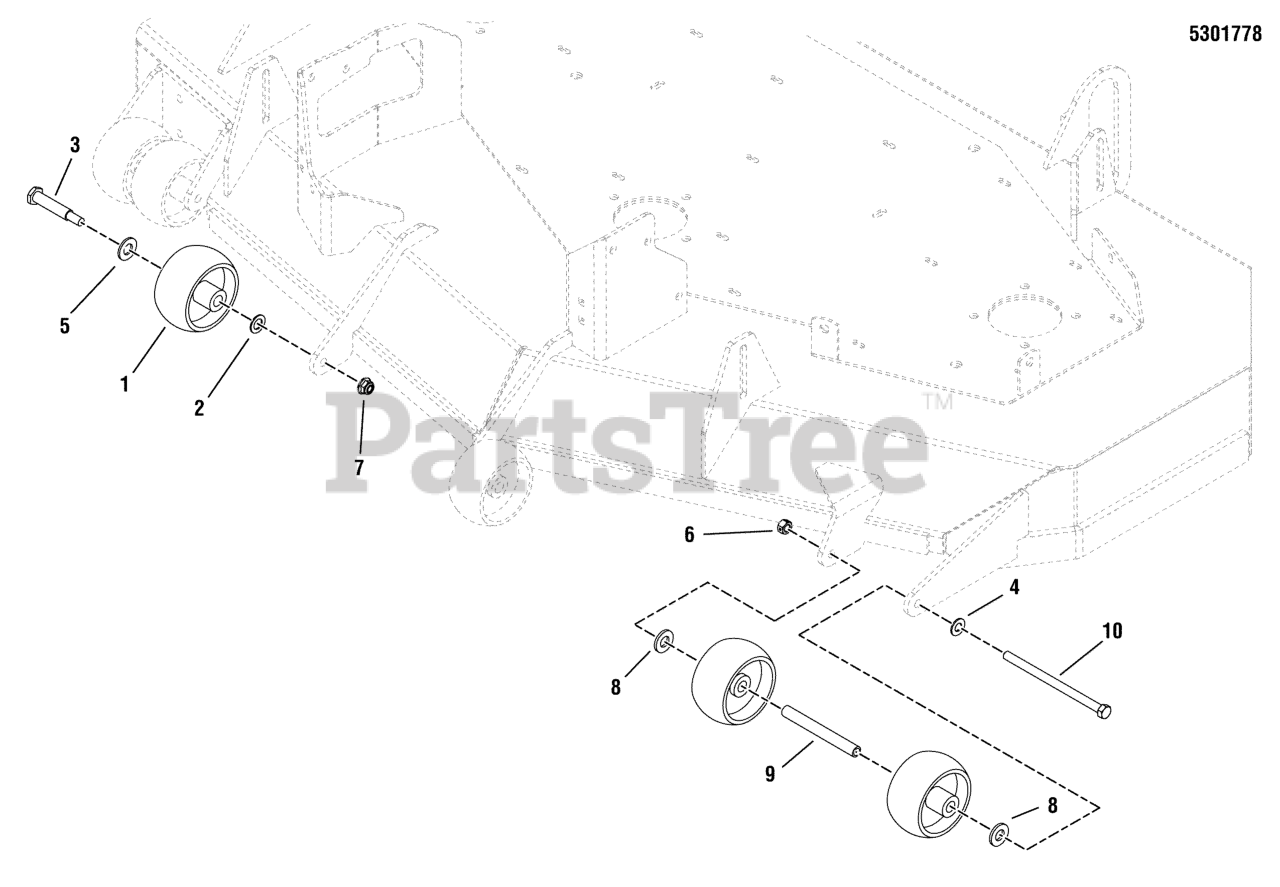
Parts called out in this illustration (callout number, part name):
1	WHEEL- 2.00 WIDE 3.88 DIA 0.531ID POLY
2	WASHER,.516IDX.875ODX.06,FLAT,ZC/CL
3	BOLT-WHEEL 3/8-16X2.781 .750 THRD YELLOW
4	WASHER, 3/8 SAE
5	WASHER, 1/2 SAE
6	NUT, 3/8-16 HEX SIDE LOCK
7	NUT, 3/8-16 HEX NYLOCK FLANGE
8	WASHER, 1/2 GD9 YZ
9	SPACER, .38 X .50 X 5.06
10	BOLT, 3/8-16 X 6" GD5 CZ
